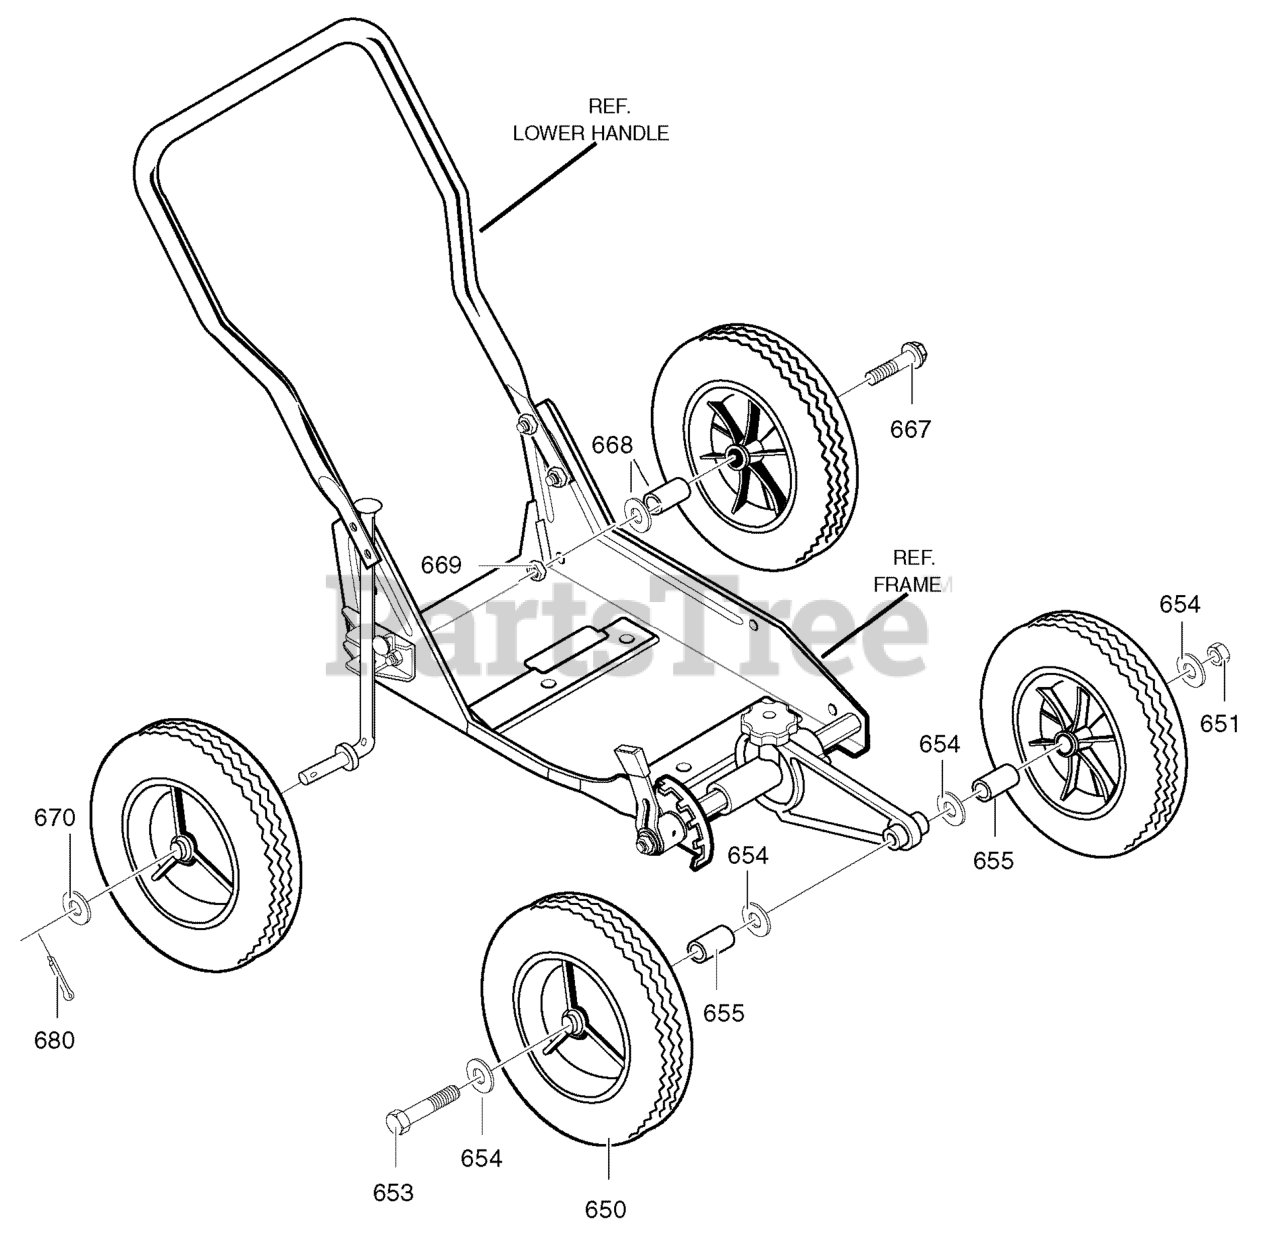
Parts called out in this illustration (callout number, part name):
650	TIRE & RIM
651	NUT, 5/16-18
653	SCREW, 5/16-18 x 4.50
654	FLATWASHER
655	SPACER, Sleeve
667	BOLT, SHH 3/8-16
668	SPACER & WASHER
669	NUT, 3/8-16
670	FLATWASHER
680	PIN, Cotter
